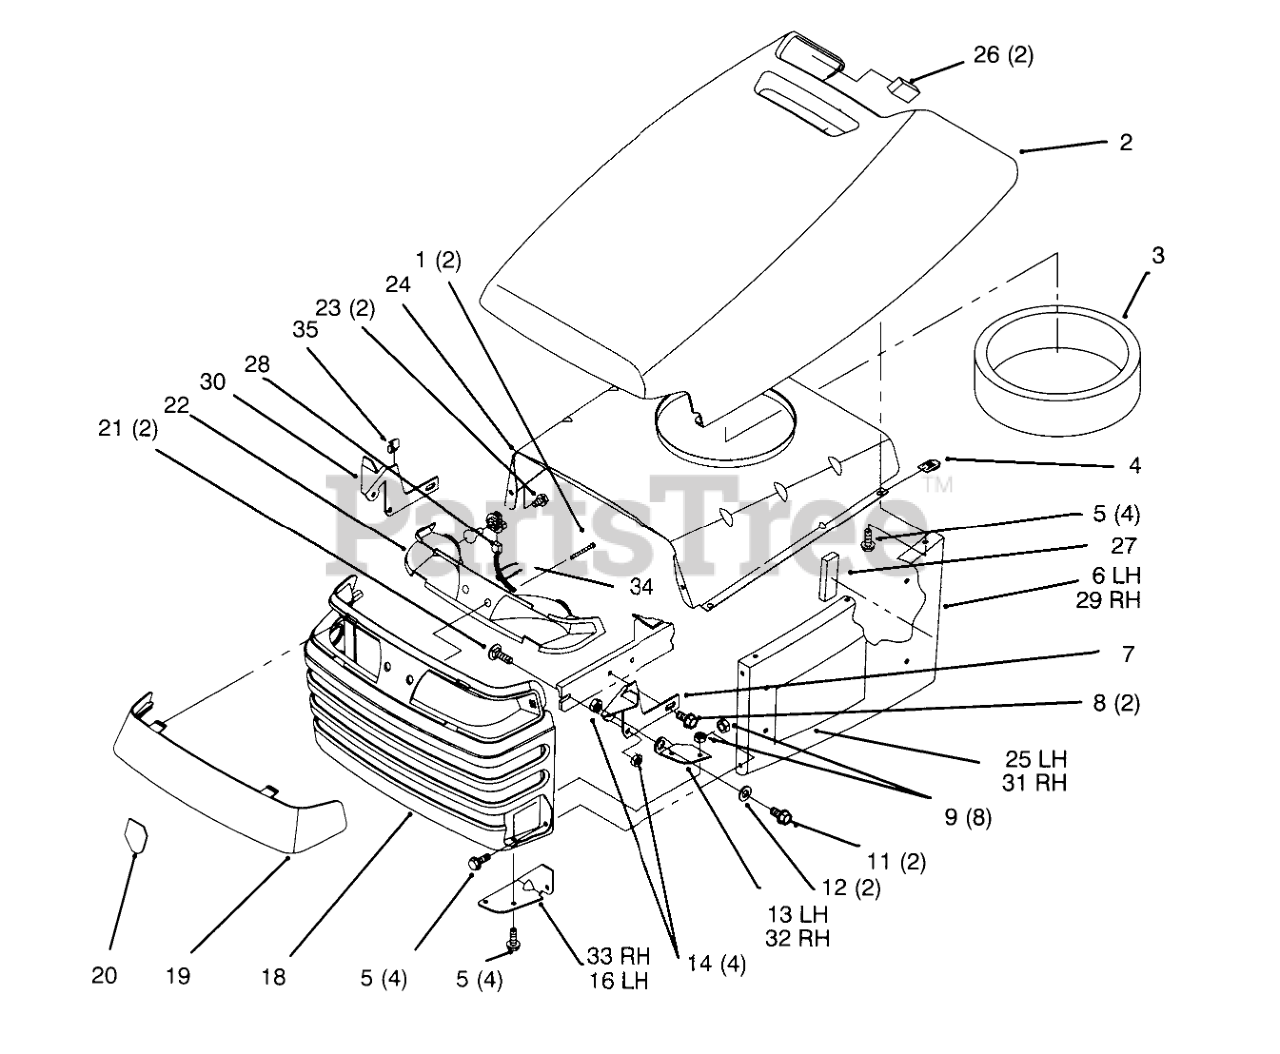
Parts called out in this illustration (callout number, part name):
2	HOOD ASM
3	SEAL-AIR INLET, TWIN
5	SCREW-HWH
6	HOOD-SIDE, LH
7	BRACKET-HINGE, LH
8	SCREW-HWHTF
9	NUT-LOCK, HHF
11	SCREW-HH
12	BUSHING
13	HINGE-HOOD, LH
14	NUT-LOCK, NI
16	BRACKET-HOOD HINGE, RH
18	Screen/Grill ASM
19	LENS - HEADLIGHT
20	EMBLEM-HORSEHEAD
21	BOLT-CARR
22	HEADLIGHT REFLECTOR ASM
23	SCREW-PLASTITE
24	BAFFLE-HOOD, UPPER
25	DECAL - LH HOOD
26	Foam-Hood
27	FOAM-SIDEPANEL
28	HARNESS-WIRE, LIGHTS
29	HOOD-SIDE, RH
30	BRACKET-HINGE, RH
31	DECAL - RH HOOD
32	HINGE-HOOD, RH
33	BRACKET-HOOD HINGE, LH
34	TIE-CABLE
35	CLIP-RETAINER, WIRE
